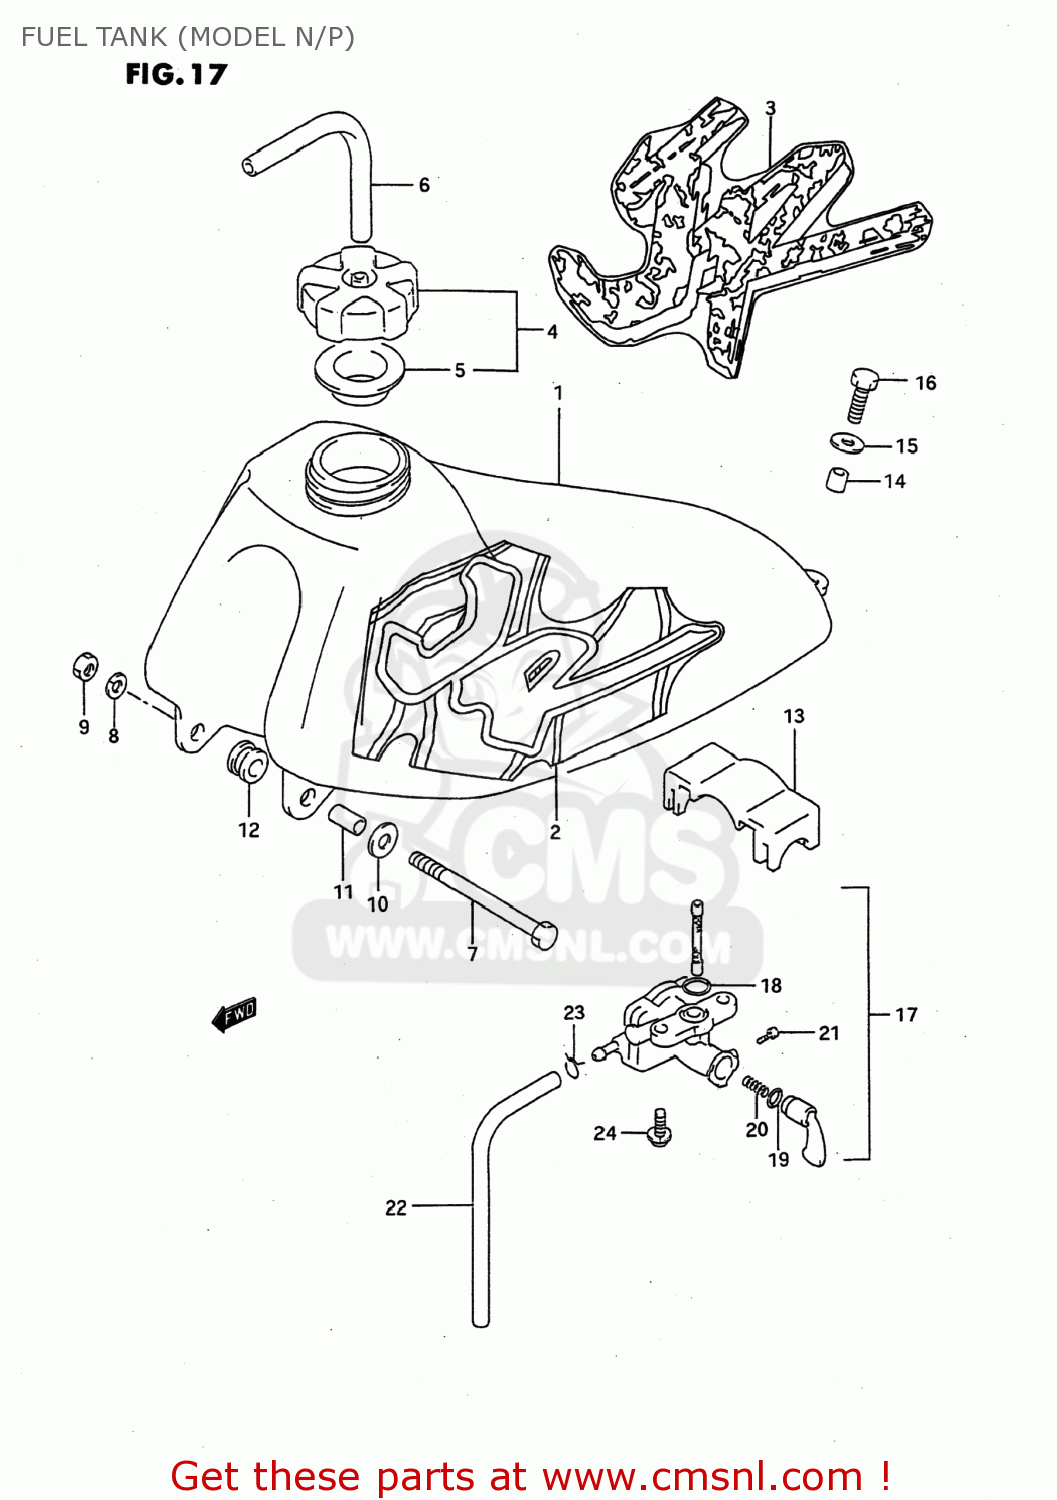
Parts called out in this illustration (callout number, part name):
1	TANK,FUEL
2	EMBLEM,FUEL TANK,LEFT
3	EMBLEM,FUEL TANK,LEFT
4	CAP,FUEL TANK FILLER
5	GASKET,FUEL TANK CAP (NAS)
6	HOSE
7	BOLT
8	WASHER,LOCK
9	NUT 6MM
10	WASHER(6.5X18X1)
11	SPACER (6.8X10X11.5)
12	CUSHION
13	CUSHION,FUEL TANK UPR
14	SPACER
15	WASHER(6.5X18X1)
16	BOLT
17	COCK ASSY,FUEL
18	O RING
19	O RING,LEVER
20	SPRING,FUEL COCK VALUE
21	SCREW
22	HOSE
23	CLIP
24	SCREW
